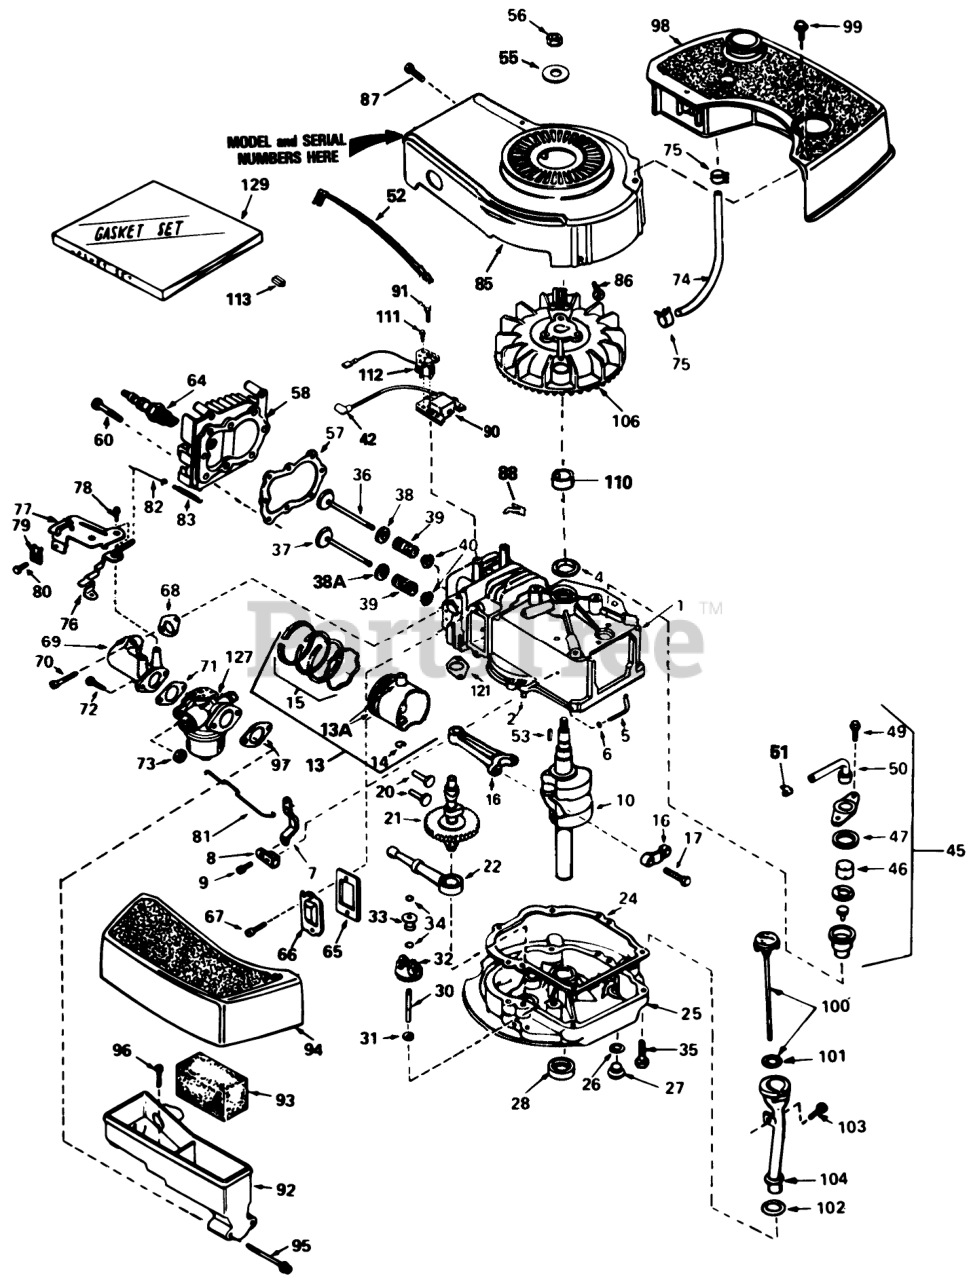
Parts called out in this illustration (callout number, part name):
1	Cylinder Assembly (Incl. Ref. #2 & 4)
2	Pin-Dowel
4	Seal-Oil
5	Rod-Governor (Incl. Ref. #6)
6	Washer-Flat
7	Governor Lever
8	Clamp-Lever, Governor
9	Screw
10	Crankshaft
13	Piston-Pin & Ring Assy. (Std.) (Incl. Ref. #13A, 14 & 15)
13	Piston-Pin & Ring Assembly (.010 oversize) (Incl. Ref. #13A, 14 & 15)
13	Piston-Pin & Ring Assembly (.020 oversize) (Incl. Ref. #13A, 14 & 15)
13A	Piston & Pin Assembly (Std.) (Incl. Ref. #14)
13A	Piston & Pin Assembly (.010 oversize) (Incl. Ref. #14)
13A	Piston & Pin Assembly (.020 oversize) (Incl. Ref. #14)
14	Ring-Retaining, Piston Pin
15	Ring Set (Std.)
15	Ring Set (.020" OS)
15	Ring Set (.010" OS)
16	Rod Assembly-Connecting (Incl. Ref. #17)
17	OA Bolt-Connecting Rod
20	Lifter-Valve
21	Camshaft(Mech.Comp. Release)
22	Oil Pump ASM
24	Gasket
25	Flange Assembly-Mounting (Incl. Ref. #26, 27, 28 & 30)
26	Gasket-Oil Drain
27	Plug Oil Drain
28	Seal Oil
30	Shaft-Governor
31	Washer-Flat
32	Gear Assembly-Governor (Incl. Ref. #31)
33	Spool-Governor
34	Ring-Retaining
35	Screw (1/4-20 x 1-1/4)
36	Valve-Intake (Std.) (Incl. Ref. #40)
36	Valve-Intake (1/32" oversize) (Incl. Ref. #40)
37	Valve-Exhaust (Std.) (Incl. Ref. #40)
37	Valve-Exhaust(1/32" oversize) (Incl. Ref. #40)
38	Seal Assy., Intake
38A	Cap-Upper Valve Spring
39	Spring-Valve
40	Cap-Valve, Spring
42	Cover-Spark Plug
45	Breather Assembly (Incl. Ref. #46 thru 51)
46	Element-Breather
47	Gasket-Breather
49	Screw (10-24 x 9/16)
50	Tube, Breaker
51	Clip, Breather
52	Wire-Ground
53	Key-Flywheel
55	Washer-Belleville
56	Nut-Flywheel
57	63573 GIL 42 SNWTHW
58	Head-Cylinder
60	Screw (5/16-18x1-1/2)
64	Plug, Spark (Autolite 458, Champion J-19LM or equiv.)
65	Gasket-Breather
66	Cover-Valve
68	Gasket-Intake
69	Pipe-Intake (Incl. Ref. #68)
70	Screw (1/4-20 x 1)
71	Gasket-Carburetor
72	Screw (1/4-28 x 7/8)
73	Nut and Lock Washer (1/4-28)
74	Line-Fuel
75	Clamp-Line, Fuel
76	Lever Control
77	Control Assembly-Speed (Incl. Ref. #76 & 78)
78	Screw, Hex Washer Hd Shoulder Self-Tap
79	Conduit
80	Screw (10-32 x 3/8)
81	Link-Throttle
82	Link Governor Spring
83	Spring Governor
85	Housing-Blower
86	Screw (1/4-20x19/32)
87	Screw (10-24 x 9/16)
88	Clip-Wire
90	Solid State
91	Screw
92	Body Air Cleaner
93	Filer, Air
94	Cove, Air Cleaner
95	Screw Fil Hd.
96	Screw, Hex Washer Hd Shoulder Self-Tap
97	Gasket-Air Cleaner
98	Tank-Fuel
99	Screw (10-32 x 35/64)
100	Dipstick-Oil (Incl. Ref. #101)
103	Screw (10-32 x 1/2)
104	Tube-Oil Fill
106	Flywheel
111	Screw (8-32x27/64)
112	Coil, Alternator
113	Connector-Body
121	Gasket Exhaust
127	Carburetor (Incl. Ref. #71)
129	Gasket Set (Incl. Items Marked )
